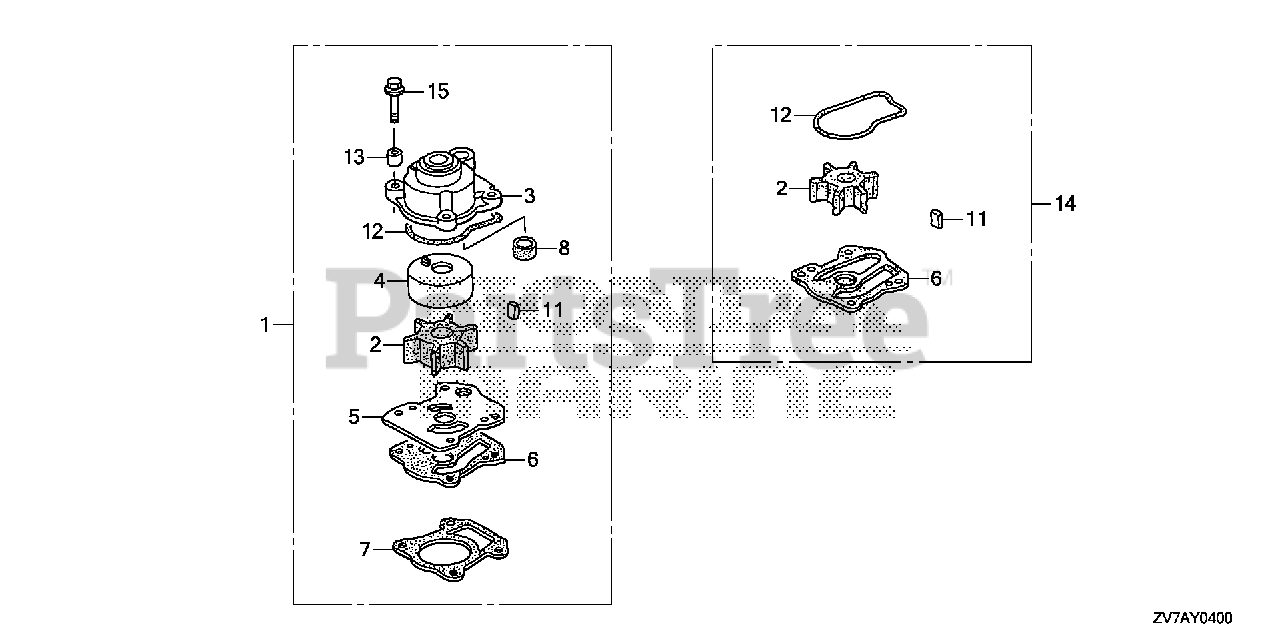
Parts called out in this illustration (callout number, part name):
1	PUMP KIT, IMPELLER
2	IMPELLER, PUMP
3	HOUSING, IMPELLER
4	LINER, PUMP
5	COVER, IMPELLER
6	GASKET B, IMPELLER
7	GASKET, WATER PUMP
8	RING, WATER TUBE SEAL
11	KEY, WOODRUFF (5MM)
12	O-RING, WATER PUMP
13	COLLAR, IMPELLER HOUSING
14	PUMP KIT, IMPELLER
15	BOLT-WASHER (6X40)
